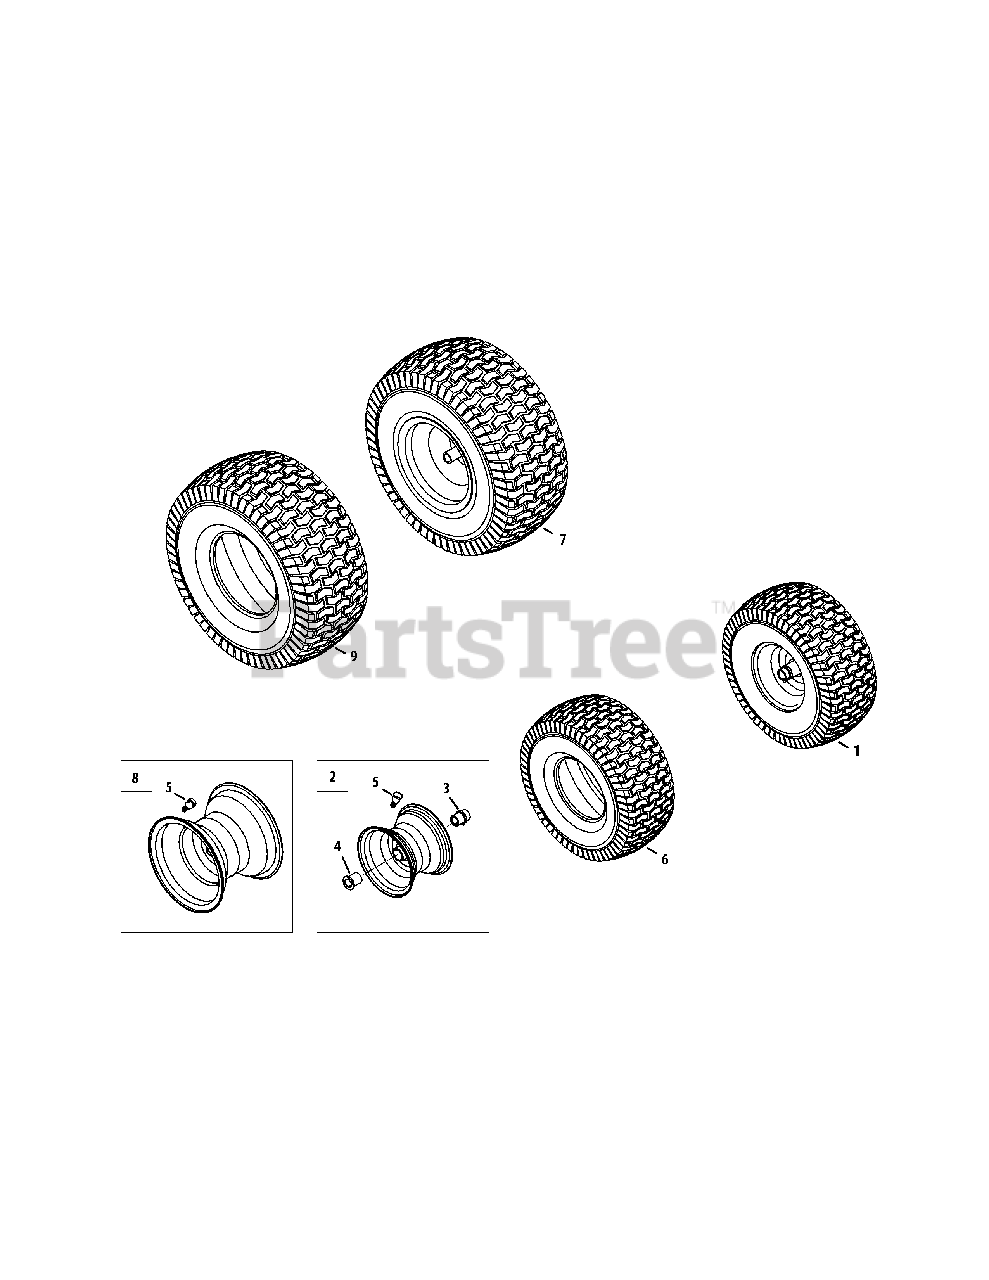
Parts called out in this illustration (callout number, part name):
1	Wheel Ass’y, Complete, 15 x 6 x 6
2	Rim Ass’y, 6.0 x 4.5, w/ Bearings
3	Bearing, Flange, .760 ID w/ Fitting
4	Bearing, Flange, .760 x 1.00 x 1.20
5	Valve, Tubeless Air
6	Tire, 15 x 6 x 6 Sq Shoulder
7	Wheel Assy, Complete, 20 x 10 x 8
8	Rim, 8.0 x 7.0 x .750 ID
9	Tire, 20 x 10 x 8 Sq Shoulder
